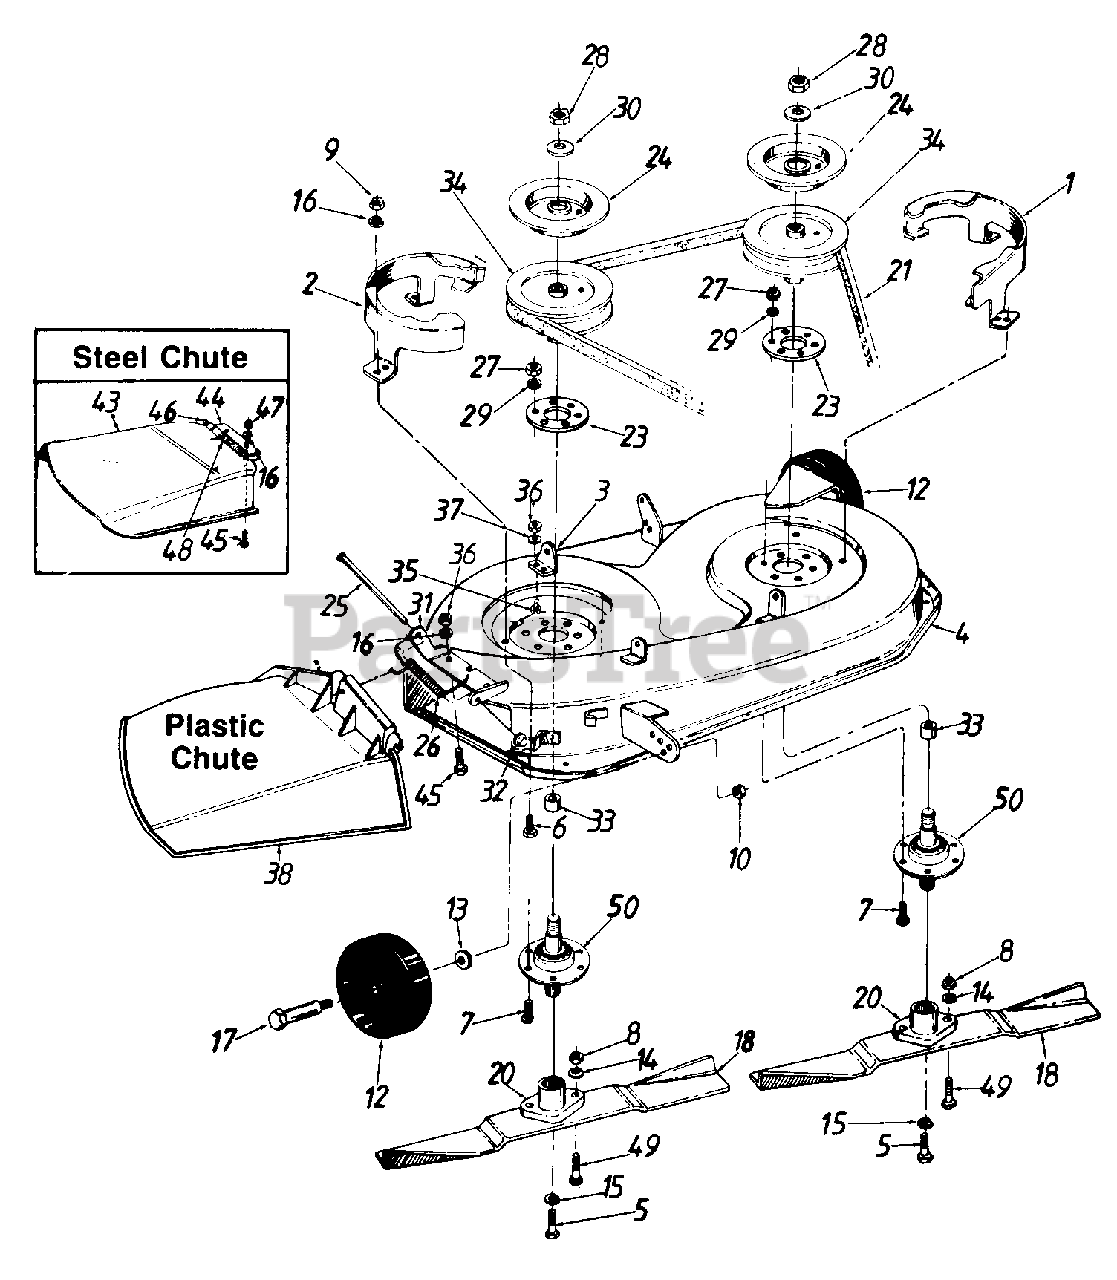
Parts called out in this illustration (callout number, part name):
5	Hex Bolt 3/8-24 x 1.0" Lg.
6	Hex Bolt 1/4-28 x .62" Lg.
7	Rib Neck Bolt
8	Hex Nut 5/16-24 Thd.
9	Hex Nut 1/4-28 Thd.
10	Hex L-Nut 3/8-16 Thd.
12	Deck Wheel
13	Bell-Wash. .380" I.D. x .88
14	L-Wash. 5/16" I.D.
15	L-Wash. 3/8" I.D. H.D.
16	Bell-Wash. .265" I.D. x .75
17	Shld. Bolt .498" Dia. x 1.53
18	High-Lift Blade
20	Blade Adapter
21	V-Belt
24	Brake Disc
25	Hinge Pin
26	Torsion Spring
27	Hex Nut 5/16-24 Thd.
28	Hex Jam Nut 5/8-18 Thd.
29	L-Wash. 5/16" I.D.
30	L-Wash. 5/8" I.D.
31	Hinge Mtg. Brkt.
32	Push Nut
33	Spacer
34	5" Dia. Pulley
35	Hex Scr. 1/4-20 x .62" Lg.
36	Hex Nut 1/4-20 Thd.
37	L-Wash. 1/4" I.D.
38	Chute Ass'y. Comp. (Plastic)
43	Chute Ass'y. (Steel)
44	Chute Bracket (Steel)
45	Truss-Mach. Scr. 1/4-20 x .75" Lg.
46	Hinge Pin
47	Hex Jam Nut 1/4-20 Thd.
48	Torsion Spring 1.14" Lg.
49	Hex Bolt 5/16-24 x 1.0" Lg.
50	Blade Spindle Complete
